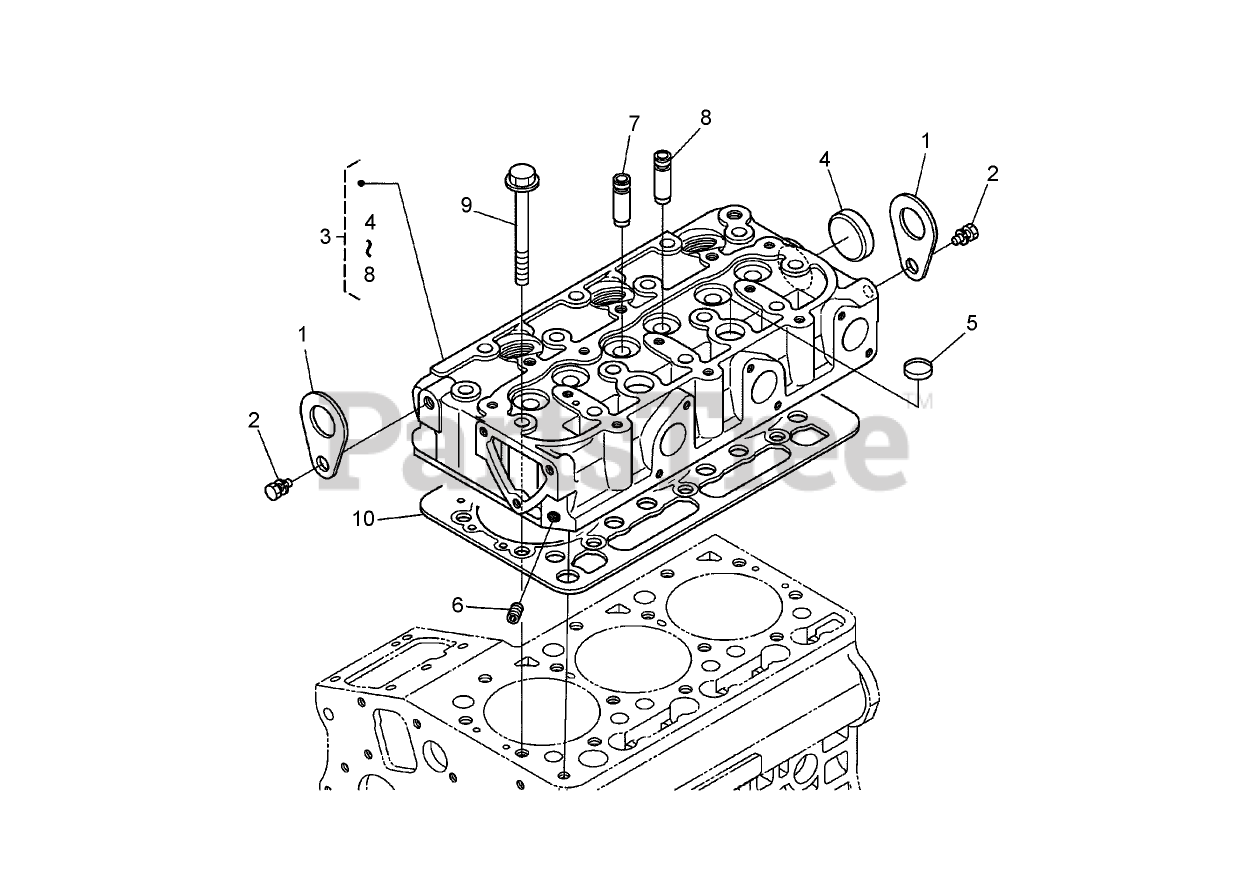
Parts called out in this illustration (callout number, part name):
1	HOOK-ENGINE
3	HEAD-CYLINDER
4	CAP-SEALING
5	CAP-SEALING
6	PLUG
7	GUIDE-VALVE, INLET
8	GUIDE-VALVE, EXHAUST
9	BOLT-HEAD, CYLINDER
10	GASKET-HEAD, CYLINDER
